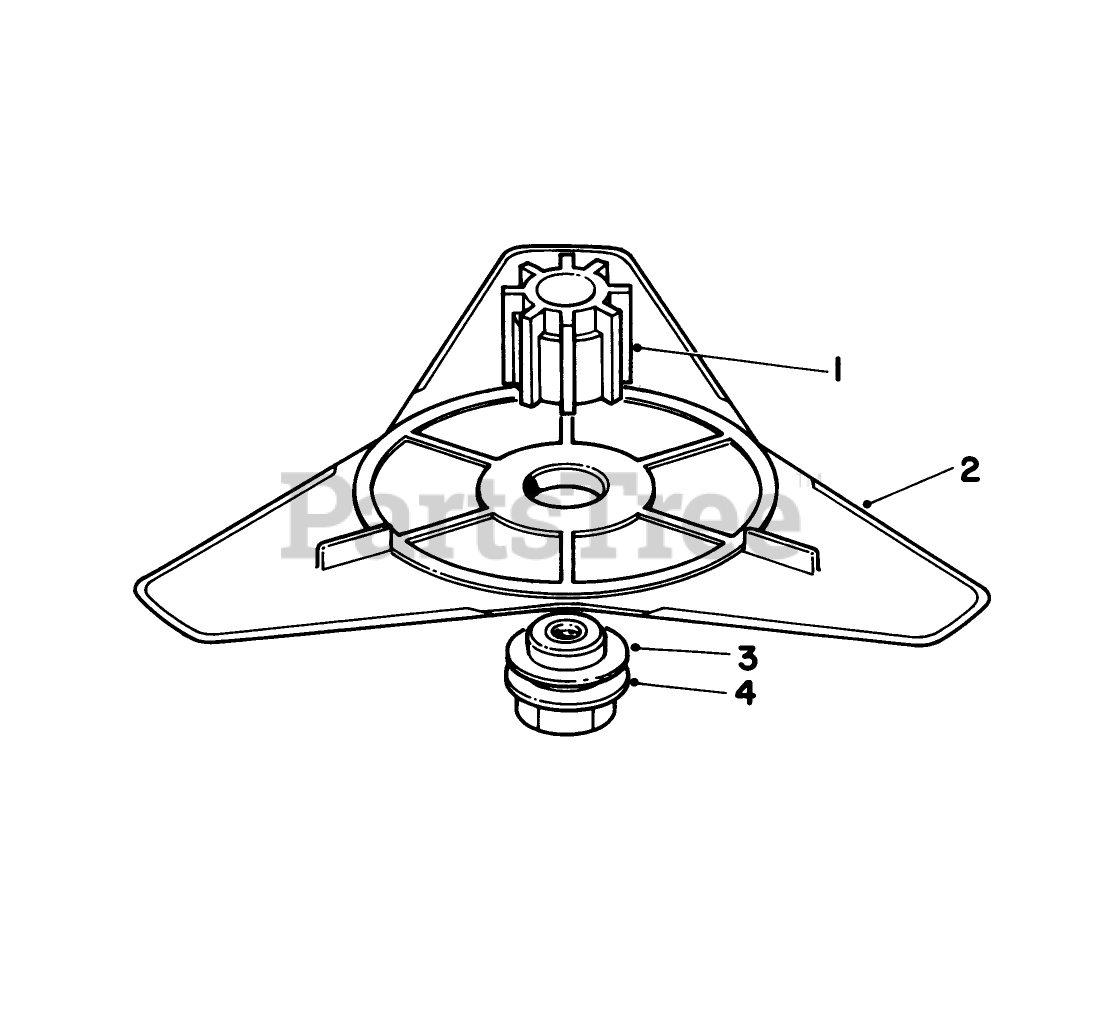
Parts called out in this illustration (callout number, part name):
1	BLADE ADAPTER
2	FLEX BLADE PKG
3	FLAT WASHER
4	ADAPTER NUT
